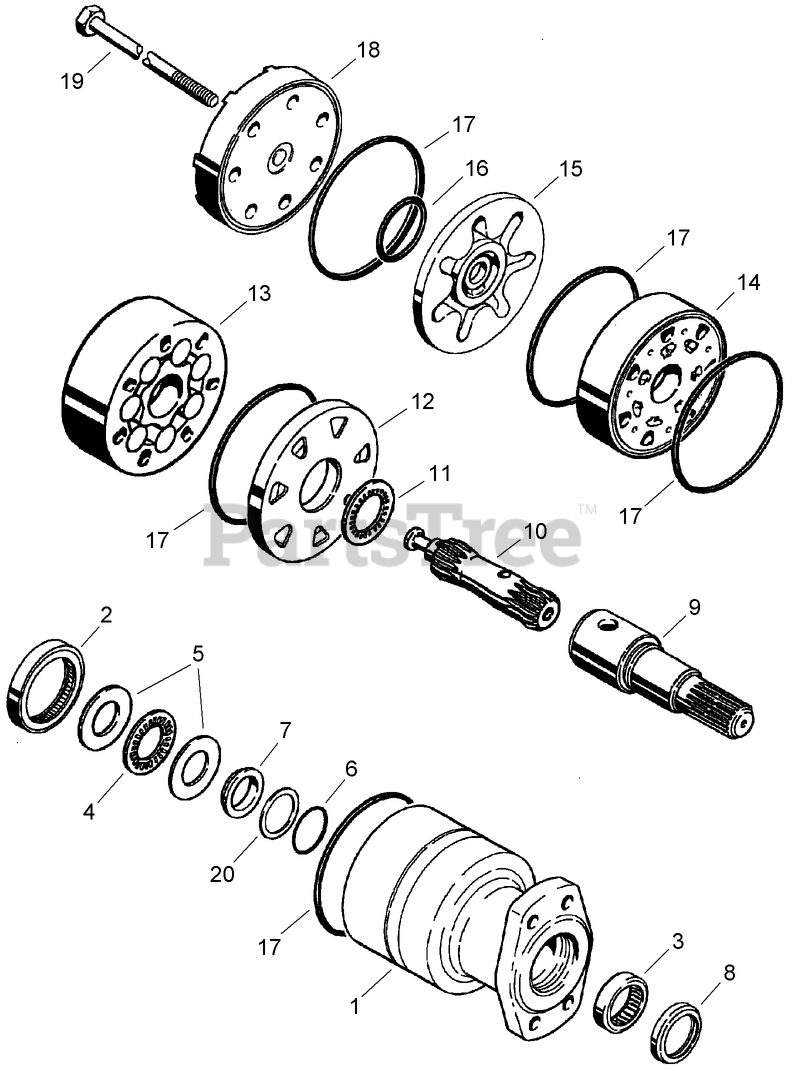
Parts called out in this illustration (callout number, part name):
1	HOUSING - Motor
2	BEARING - Needle, Large
3	BEARING - Needle, Small
4	BEARING - Thrust, Shaft
5	WASHER - Thrust, Bearing
6	RING - Backup, Seal, Housing
7	SEAL - Housing
8	SEAL - Shaft, Outer
9	SHAFT - Coupling
10	LINK - Drive
11	BEARING - Thrust, Link
12	PLATE - Wear
13	ROTOR - Drive Motor
14	MANIFOLD - Plate
15	COMMUTATOR - Includes Center Ring
16	RING - Seal, Small
17	RING - Seal, Large
18	COVER - End
19	BOLT - Hex, Special
20	WASHER - Drive Motor, Flat, 1-13/32 x 1-21/32 x 1/64
